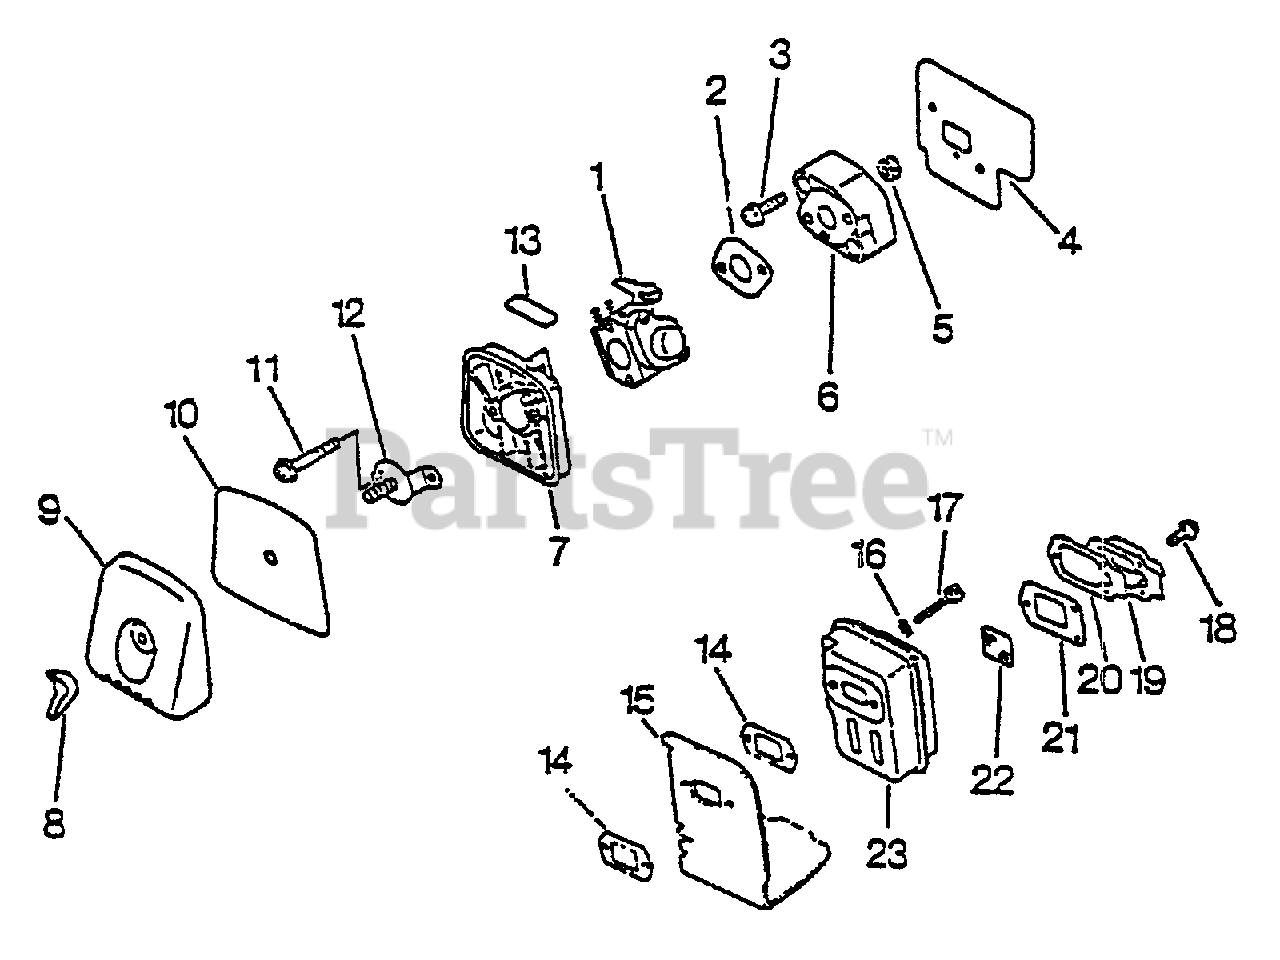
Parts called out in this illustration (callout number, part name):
1	CARBURETOR C1U-K26
2	GASKET, INTAKE
3	SCREW - 5X22
4	GASKET, INTAKE
6	INSULATOR, INTAKE
7	AIR FILTER CASE KIT - BLACK
8	WINGNUT - 6
9	COVER, AIR FILTER - BLACK
10	FILTER, AIR
11	SCREW - 5X64
12	PLATE, PREVENT
13	LABEL - CHOKE
14	GASKET, EXHAUST
15	SHIELD, EXHAUST
16	WASHER - 5
17	SCREW - 5X55
18	SCREW - 4X10
19	GUIDE, EXHAUST - INNER
20	GASKET, EXHAUST - INNER
21	GASKET, EXHAUST
22	SCREEN, SPARK ARRESTOR
